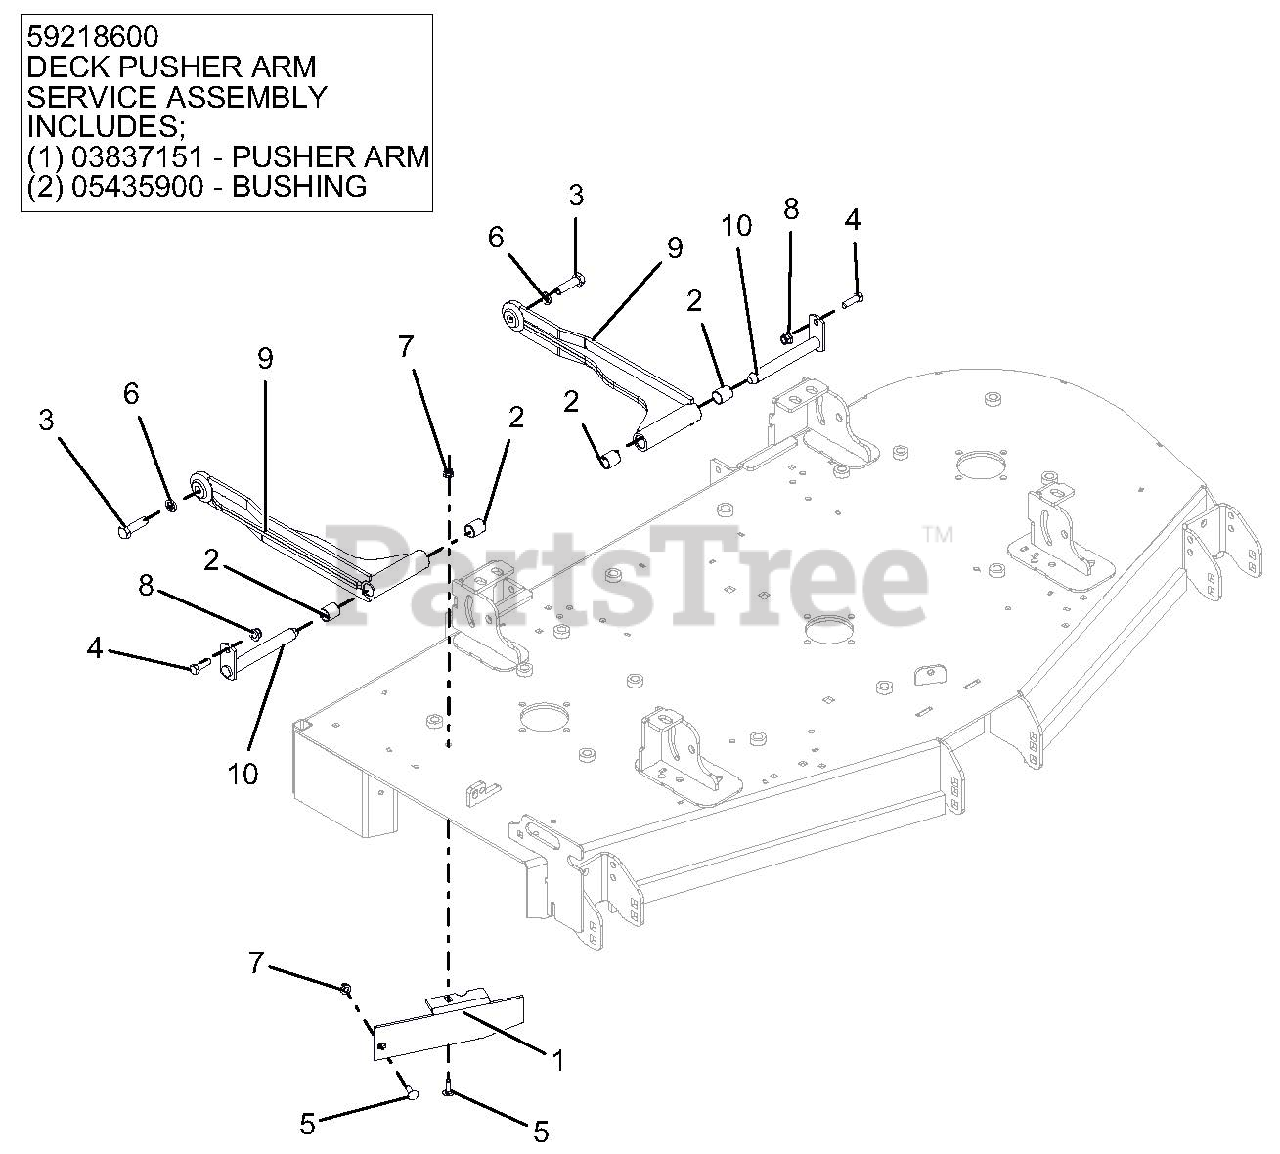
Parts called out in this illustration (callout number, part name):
1	BAFFLE, 60" DISCHARGE
2	BRG, .750 X .875 X 1.000
3	BLT-HEX .50-13X1.75 GR5 YWZC EP80
4	BLT-HEX .38-16X1.25 GR5 YWZC
5	BLT-RDHDSQSHNK .31-18X1.00 G5 Y
6	WSHR-LK .50X.125 REG YWZC
7	NUT-LK-NYL-FLG .31-18 YWZC
8	NUT-LK-NYL-FLG .38-16 YWZC
9	WMT, DECK STABILIZER ARM
10	WLDMT, MOWER MTG. PIN
11	DECK PUSHER ARM SERVICE ASSEMBLY
12	PUSHER ARM
13	BUSHING
